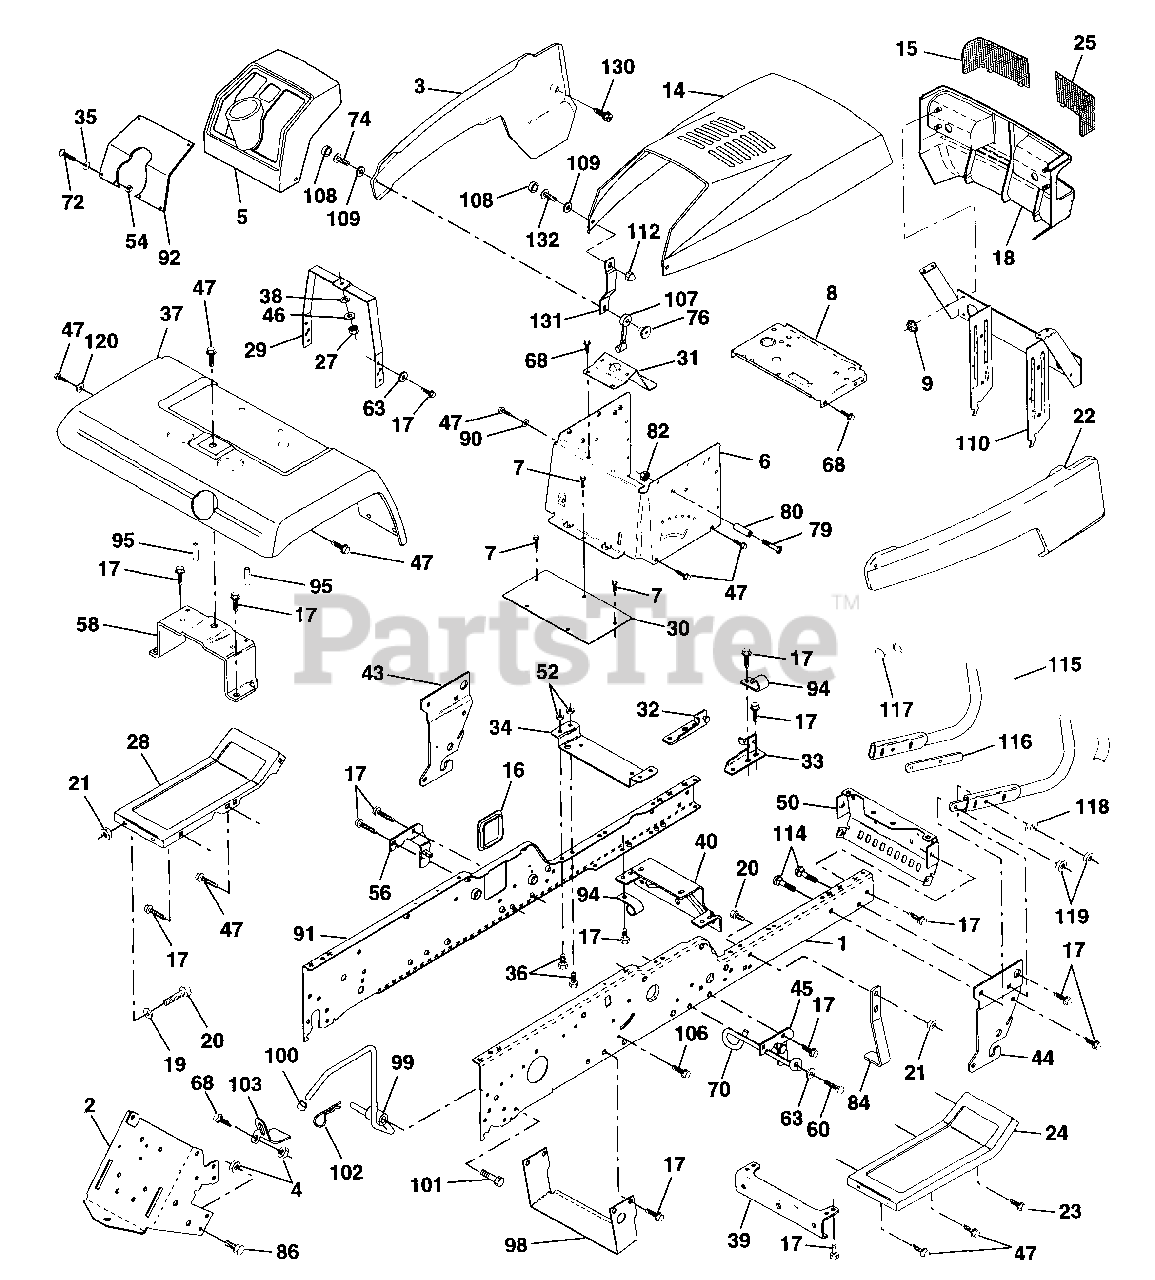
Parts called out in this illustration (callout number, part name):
1	Rail, Frame RH
2	Drawbar, Gt
3	Panel Asm., Side LH
4	Nut, Lock Hex 7/16 Unc
5	Dash, Plastic Black
6	Dash 1-PCS, Lower
7	Screw, Thd Cut 1/4-20 x 1/2
8	Support, Battery
14	Hood Asm., Pnt
15	Lens, Headlight LH
16	Cover, Access
17	Screw, Thdrol 3/8-16 x 3/4
19	Washer 13/32 x 13/16 x 12 Ga.
20	Bolt, Fin Hex 3/8-16 x 1
21	Nut, Crownlock 3/8-16 Unc
22	Panel Asm., Side RH
23	Screw Thdrol. 3/8-16 x 1 Ty-TT
24	Footrest, RH
25	Lens Headlight RH
27	Nut Fin Hex 1/4-20
28	Footrest, LH
29	Bracket, Support Dash
31	Brace, Support Steering
32	Bracket Asm., Frame Pivot Lh
33	Bracket Asm., Frame Pivot Rh
34	Bracket, Engine Support Rear
35	Washer 11/32 x 11/16 x 16 Ga.
36	Bolt, Fin Hex 5/16-18 x 3/4
37	Fender, Pnt.
38	Washer, Lock 1/4
39	Bracket, Axle Front
40	Bracket, Support Axle/Engine
43	Bracket, Spnsn Front Lh
44	Bracket, Spnsn Front Rh
45	Bracket Asm., Susp Chassis Rh
46	Washer 9/32 x 3/4 x 16 Ga.
47	Screw Thdrol 3/8-16 x 1/2
50	Bracket, Chassis Front
52	Locknut, Hex W/Ins 5/16-18 Unc
54	Nut 5/16-18
56	Bracket Asm., Susp Chassis Lh
58	Bracket Asm., Fender
60	Screw Thdrol 3/8-16 x 1-1/4
63	Washer 13/32 x 1 x 14 Ga.
68	Screw, Thdrol 5/16-18 x 1/2
70	Guide, Belt Mid Span
72	Screw, Mach Trhd 5/16-18 x 3/4
74	Screw, Machine #10-24
76	Nut, Weld #10-24
79	Screw, Machine #10-24 x 1/4
80	Spacer, Split
82	Nut #10-24
84	Stop, Over Center 44" 20/23" T. 94
86	Bolt, Fin Hex 7/16-14 Unc x 1
90	Washer, Lock External Tooth 3/8
91	Rail, Frame Lh
92	Plate, Silkscreen Dash
94	Clip, Fuel Line
95	Push Nut, Nylon
98	Bracket Chassis Skid
99	Rod Asm. Bypass
100	Cap Brake Parking Red
101	Screw Thdrol. 3/8-16 x 1-3/4
102	Retainer Spring 1"
103	Bracket Lock Bypass
106	Screw Thdrol. Hex Hd Zinc Mur
107	Latch, Chute Blk
108	Cap, Snap Black
109	Cap, Washer Snap
110	Pivot Asm. Grille/Hood Husq. VGT
112	Nut, Acorn, Hex #10-24
114	Bolt, Carriage 3/8-16 x 1-1/4
115	Bumper Asm.
116	Bracket Extension Bumper
117	Plug Plastic
118	Washer 13/32 x 13/16 x 16 Ga.
119	Nut Crownlock 3/8-16 UNC
120	Washer 13/32 x 1 x 16 Ga.
130	Screw, SLTD Hex Hd. W/PI Washer
131	Bracket Support Hood/Panel YP
132	Screw Truss Hd. #10-24 x 3/8
